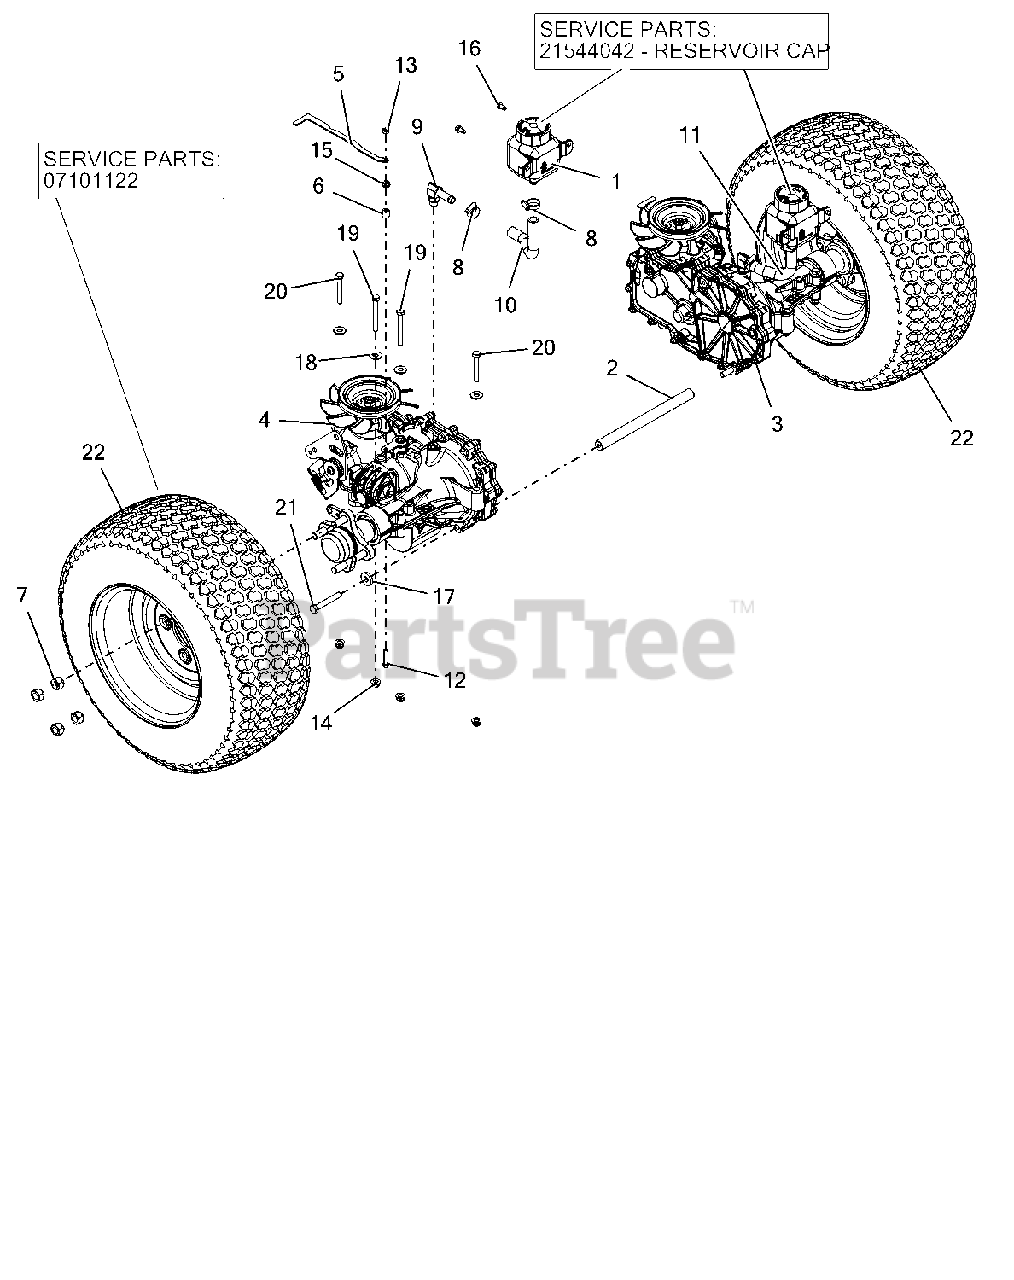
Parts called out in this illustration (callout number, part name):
1	TANK, EXPANSION ZT2800
1	RESERVIOR CAP
2	ROD, TRANSAXLE BRACE-9.27 (BLACK)
3	TRANSAXLE, ZT2800 - LH
4	TRANSAXLE, ZT2800 - RH
5	BRKT, VALVE DUMP -XL
6	BSHG, SLV .265X.500X.500
7	NUT, LUG .500-13
8	CLAMP, .88 DIA HOSE
9	FITTING, HYD (90 DEG)
10	HOSE, EXPANSION TANK-FORMED RH
11	HOSE, EXPANSION TANK-FORMED LH
12	BLT-HEX .25-20X1.25 GR5 YWZC
13	NUT-LK-CTR-JAM .25-20 YWZC
14	NUT-LK-NYL-FLG .31-18 YWZC
15	@NUT-SPNLK-FLG .25-20 YWZC
16	SCR-TAP .25-20X.50 HWH TR YWZ
17	WSHR-FL-STL .406X1.00X.188 YWZC
18	WSHR-FL-STL.38X.875X.083 YWZC
19	BLT-HEX .31-18X2.75 GR5 YWZC
20	BLT-HEX .31-18X2.25 GR5 YWZC
21	BLT-HEX .38-16X2.50 GR5 YWZC
22	TIRE, 20X8.00-10
22	ASSM TIRE\WHEEL, 20 X 8.00 - 10
